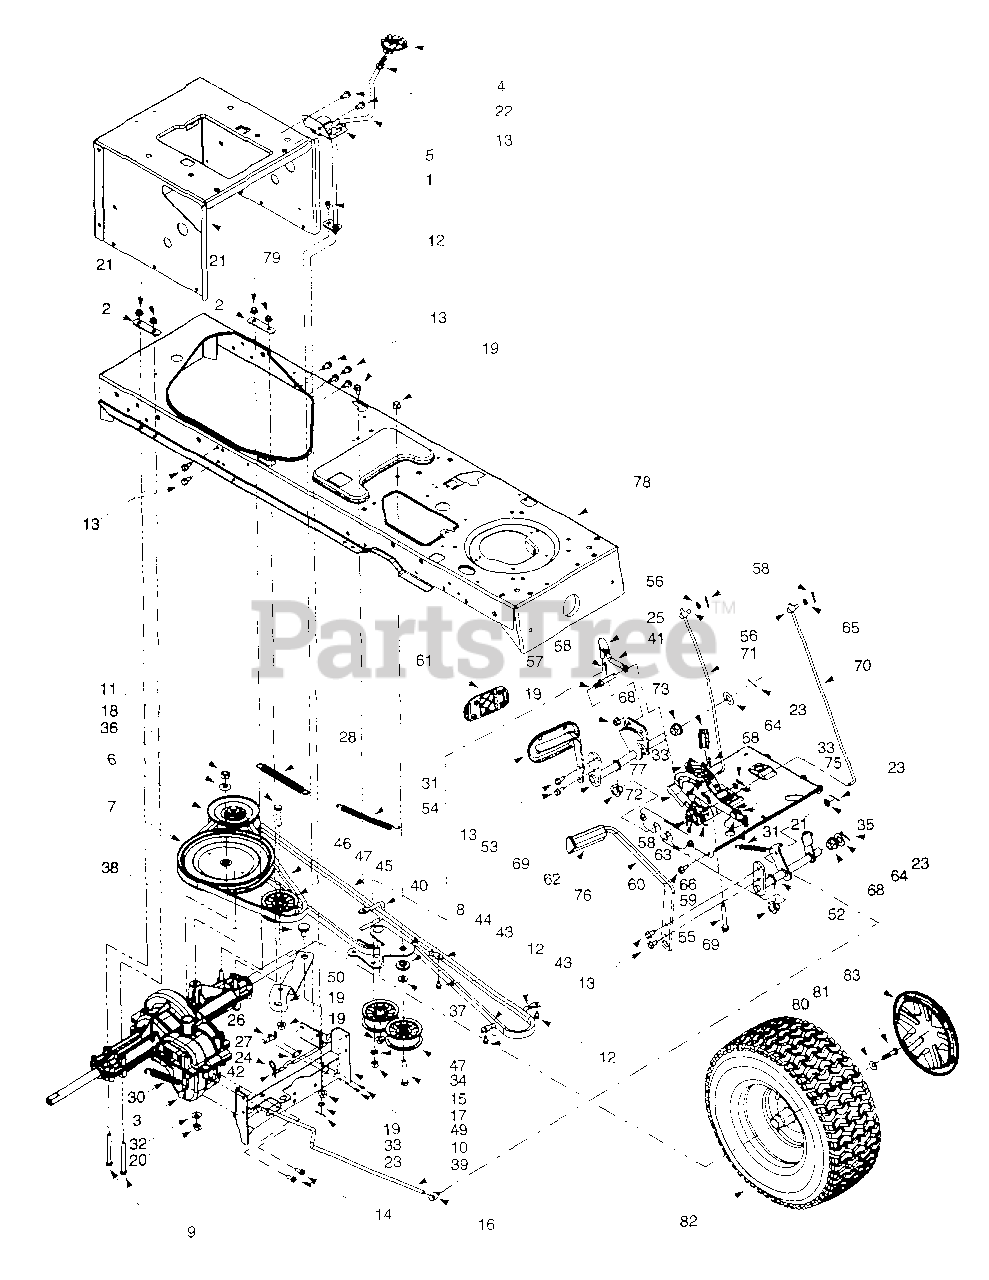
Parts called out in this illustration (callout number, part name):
1	Shift Lever Bracket
3	Single-speed Transmission Assembly
4	Shifter Knob
5	Shift Lever
6	Variable-speed Pulley Assembly
7	Transmission Pulley, 8.5 x .5-36
8	Double-idler Bracket
9	Hex Cap Screw, 5/16-18 x 3
10	Self Tapping Screw, #8-18 x .5
11	Hex Cap Screw, 3/8-16 x 1.75
12	Self Tapping Screw, 1/4-20 x .5
13	Self Tapping Screw, 5/16-18 x .625
14	Self Tapping Screw, 1/4-20 x .75
15	Hex Cap Screw, 3/8-16 x 2.25
16	Ferrule, 5/16-18
17	Hex Nut, 3/8-24
18	Hex Nut, 7/16-20
19	Flange Lock Nut, 3/8-16
20	Hex Nut, 3/8-16
21	Flange Lock Nut, 5/16-18
22	Jam Nut, 3/8-16
23	Cotter Pin
24	Internal Cotter Pin
25	Ball Joint, 3/8-24
26	Short Spring Switch
27	Insulator Nut Plate
28	Extension Spring, .62 Dia. x 6.12
30	Extension Spring, .59 OD x 4
31	Extension Spring, .50 Dia. x 6.37
32	Bell Washer, .401 x .87 x .063
33	Flat Washer, .385 x .62 x .063
34	Lock Washer, 3/8
35	Flat Washer, 5/16
36	Bell Washer, .45 x 1.0 x .602
37	Flat Washer, .407 x .812 x .135
38	Shoulder Screw, .625 x .217
39	Brake Rod
40	Belt Guard
41	Idler Adjustment Rod, 3/8
42	Shift Rod
43	Belt Guard Rod
44	Shoulder Spacer, .38 ID
45	Variable-speed Belt
46	Drive Belt
47	Flat Idler, 2.75 OD
52	Brake Control Assembly
53	Speed Control Assembly
54	Auto Drive Pedal Assembly
55	Self Tapping Screw, 5/16-18 x 2.5
56	Ferrule, 1/4-20
57	Pin, 3/8-16 x 2.43
58	Cotter Pin
59	Compression Spring,,34 OD x 1.0
60	Extension Spring, .50 OD x 1.41
61	Auto Drive Pedal Pad
62	Brake Pedal Pad
63	Flat Washer, .281 x .5 x .0625
64	Flat Washer, .64 x 1.24 x .06
65	Flat Washer, .344 x .062 x .03
66	Shoulder Screw, .437 x 1.62
68	Hex Flange Bearing
69	Split Hex Flange Bearing
70	Cruise Control Rod
71	Brake Lock Control Rod
72	Cruise Latch
73	Spacer, 5/16 x 1.54
75	Auto Drive Lockout Bracket
81	Hex Cap Screw, 5/16-24 x .75
83	Hub Cap, Yellow w/ Sprig Logo
